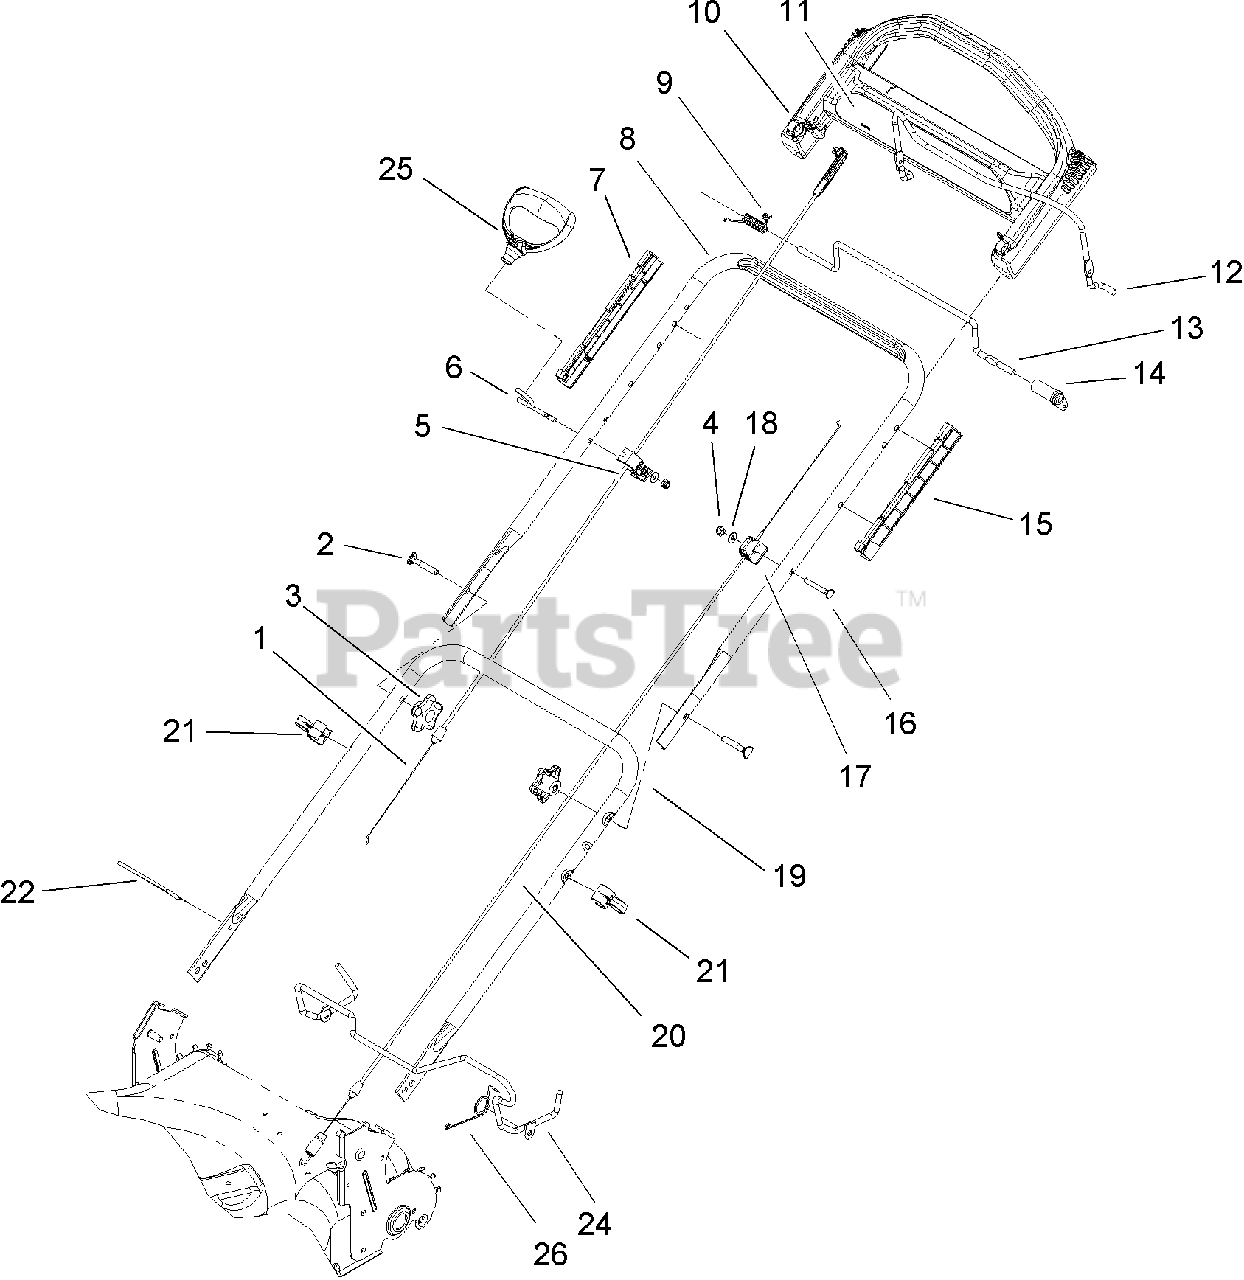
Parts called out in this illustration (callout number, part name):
1	CABLE-BRAKE
2	SCREW-HANDLE
3	KNOB-HANDLE
4	NUT-LOCK, NI
5	ANCHOR-CABLE
6	GUIDE-ROPE
8	Handle-Upper
9	Spring-Torsion
10	HANDLE-CONTROL, GRAY
11	DECAL-HANDLE
12	Bail-Brake
13	BAR-CONTROL, TRACTION
14	LEVER-TRACTION
16	SCREW-HH
17	ANCHOR-CABLE, UPPER
18	WASHER-FLAT
19	HANDLE-LOWER
20	Cable-Traction
21	Guide-Cable
22	STRAP-TIE
24	RELEASE LEVER ASM
25	HANDLE-RECOIL
26	SPRING-TORSION
